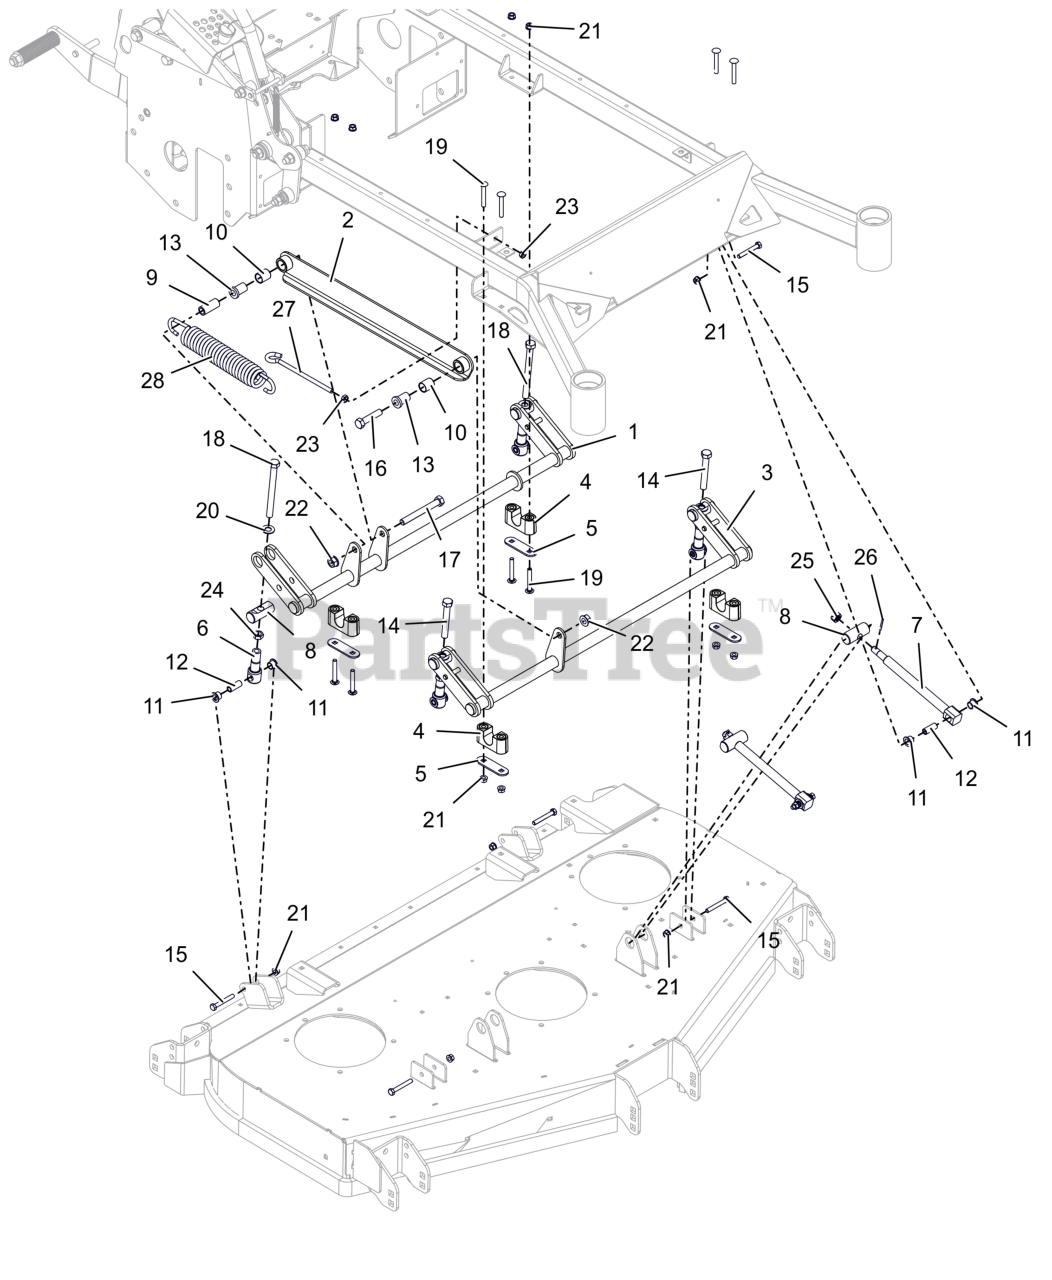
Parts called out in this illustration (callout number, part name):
1	WLDMT- DECK LIFT
2	LINK- DECK LIFT (BLACK)
3	WLDMT- DECK LIFT - FRONT
4	ASM-BUSHING, DECK LIFT
5	PLATE, BEARING SUPPORT
6	LINK, DECK LIFT FORMED
7	DRAG,LINK-HD
8	PIN, DECK LIFT
9	BUSHING- .515 X 1.000 X 3.088
10	BRG- .750 X .875 X 1.000
11	BSHG, FLANGED .50X.625X.50X.062
12	SPCR, .31X.50X1.265
13	BSHG-FLG .515X.746X1.290X1.000
14	BLT, HEX .50-13X3.50F G5 ZCC
15	BLT, HEX .31-18X2.25 G5 ZCC
16	BLT, HEX .50-13X2.25 G5 ZCC
17	BLT, HEX .50-13X4.25 G5 ZCC
18	BLT, HEX 0.5-13X5.5F GR5 ZCC
19	BLT, RHSSN.31-18X2.25 G5 ZCC
20	WSHR, FLT .557X1.040X.102 ZCC
21	NUT,LK-CTR-FLG .31-18 GF ZCC
22	NUT-LK-CTR-FLG .500-13 GG ZCC
23	NUT-JAM .375-16 G2 ZCC
24	NUT-JAM .500-13 G2 ZCC
25	NUT-SL .50-13
26	PIN,CTR.12X1.25EXTPRSQCT ZC120
27	BOLT, .38-16X6.00 .62 DIA EYE
28	SPRG-EXTEN - .273X1.853X10.125
